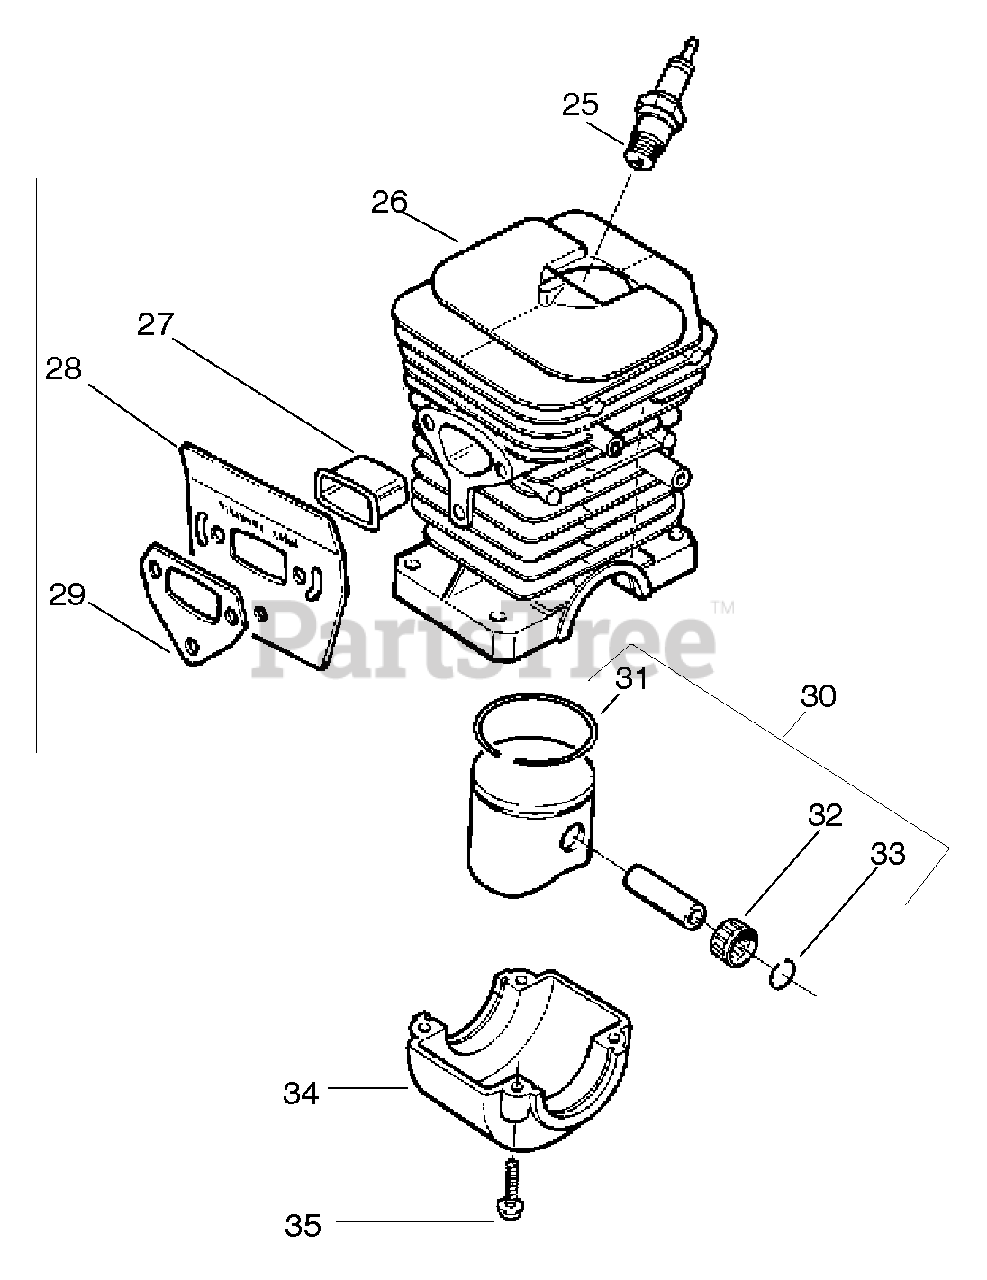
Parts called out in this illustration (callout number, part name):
25	Spark Plug (RCJ-7Y)
27	Heat Insulator
28	Muffler-Plate
29	Muffler Gasket
30	Piston Kit (136)
30	Piston Kit (141)
31	Piston Ring (136)
31	Piston Ring (141)
32	Piston Pin Bearing
33	Piston Pin Retainer
34	Cap-Crankcase
